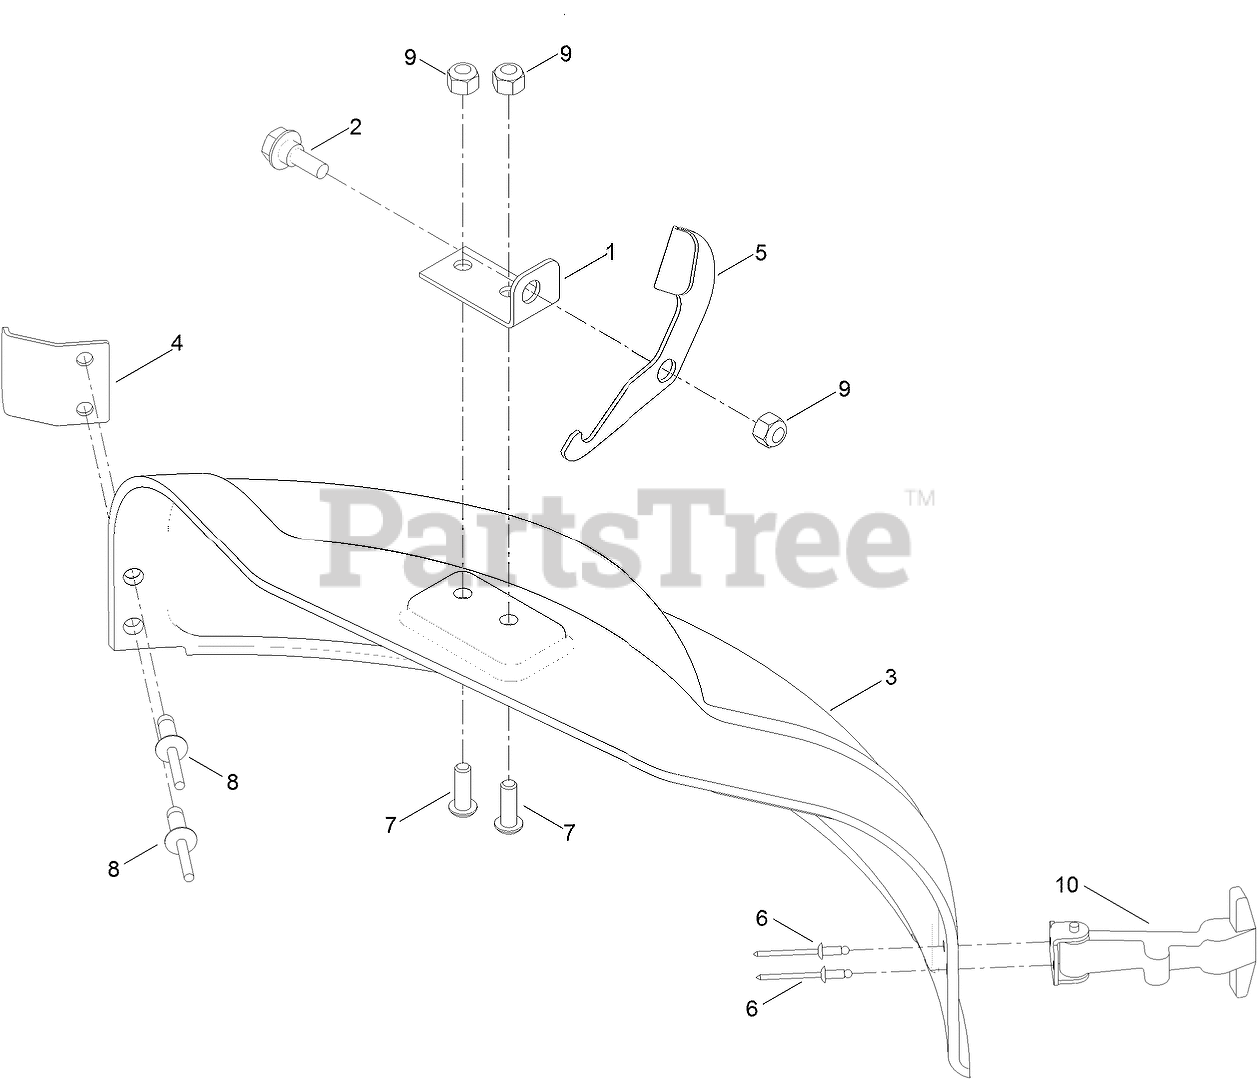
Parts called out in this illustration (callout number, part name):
1	PLATE-PIVOT
2	SCREW-SHOULDER,HWH
3	PLUG-MULCH, 42 INCH
4	BRACKET-ELBOW
6	RIVET-POP
7	SCREW-HSBH
8	RIVET-BLIND
9	NUT-LOCK, NI
10	HANDLE ASM
